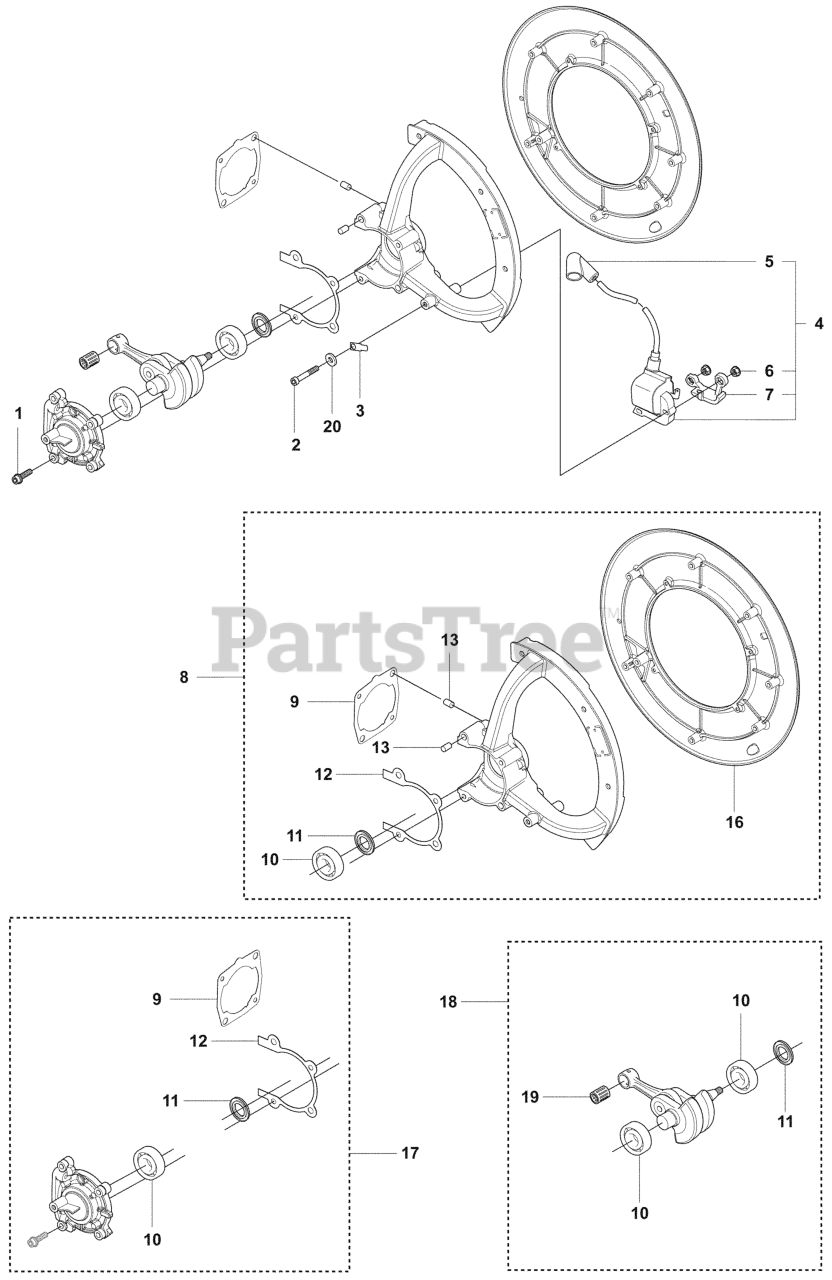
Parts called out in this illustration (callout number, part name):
1	SCREW
3	FLAT PIN
4	IGNITION SYSTEM
5	SPARK PLUG CONN. KIT
8	CRANKCASE KIT
10	BALL BEARING-6202-C3 SKF
13	SLEEVE
18	CRANKSHAFT
19	BEARING
20	WASHER 4.2X9
